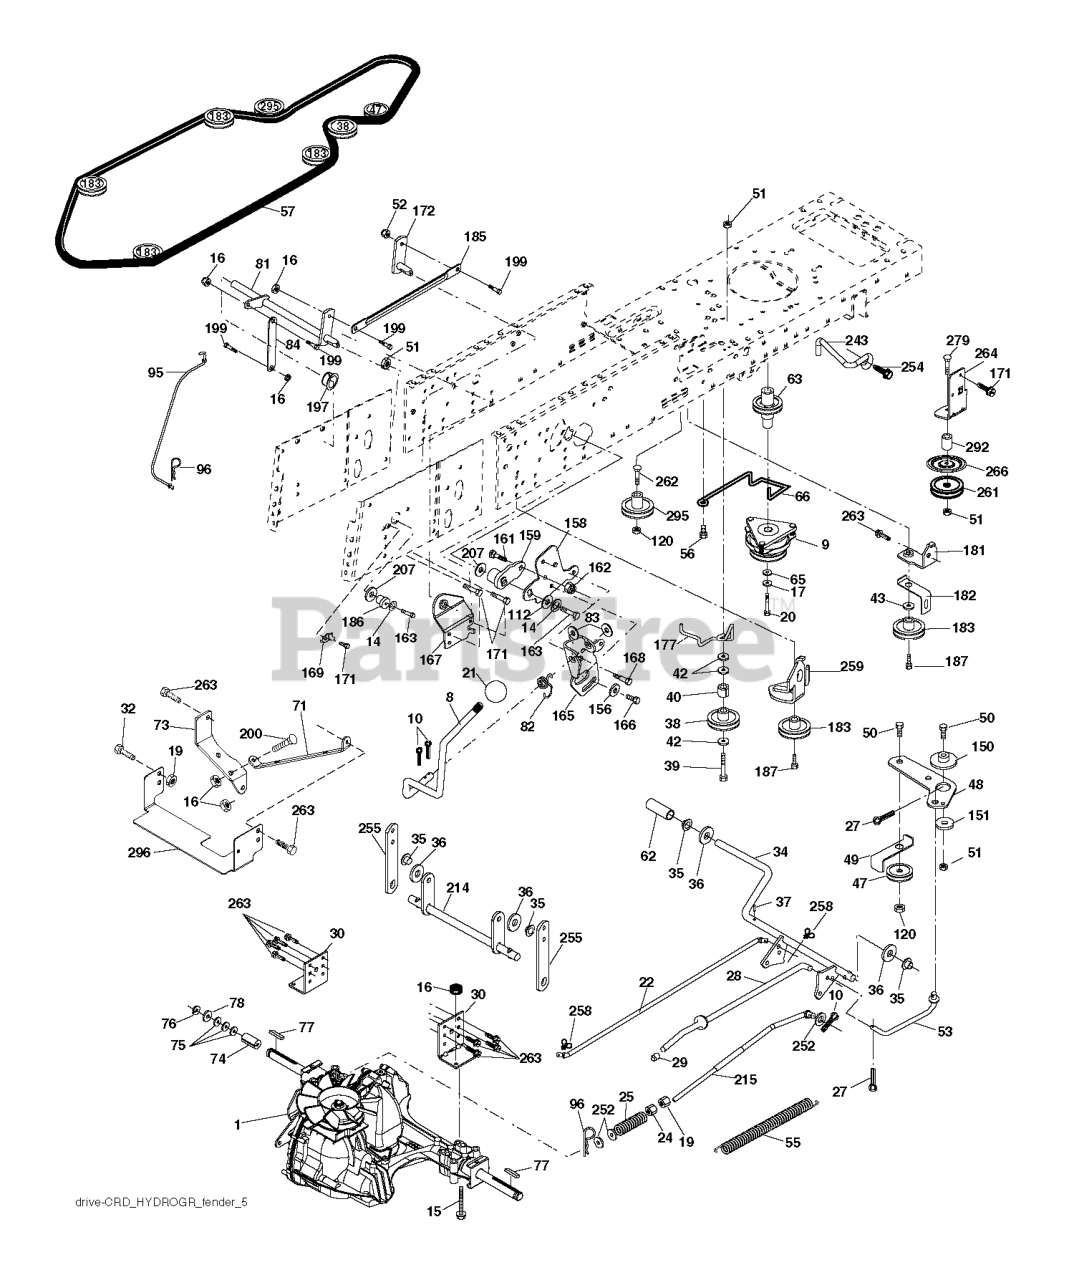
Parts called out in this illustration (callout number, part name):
8	ROD SHIFT FENDER ADJUST LT
9	CLUTCH.ELECTRIC.OGURA.EURO.
10	PIN COTTER
14	LOCKWASHER
15	BOLT HEX 5/16-18 GR 5
16	NUT.71038.31-18.HEX.NYLOCK
19	NUT
20	BOLT HEX 7/16-20X4-1/4"
21	KNOB.DUCKHEAD.1/2
22	ROD
24	NUT
25	SPRING BRAKE ROD
27	COTTER PIN
28	ROD, PARKING BRAKE
29	CAP
30	BRKT, TRNSXLE MNT 20"
32	BOLT D
34	SHAFT, FOOT PEDAL
35	BEARING.NYLON
37	DRIVE PIN
38	PULLEY.FLAT
42	WASHER
47	IDLER PULLEY
48	BELLCRANK, CLUTCH
49	RETAIN BELT
50	BOLT.3/8-16X1.50
52	LOCKNUT
53	LINK.CLUTCH.7.66.2005
55	SPRING, RETURN LT
56	SCREW.3/8-16
57	V-BELT 113"
62	PEDAL COVER T
63	PULLEY.ENGINE.CVX.LT
65	LOCKWASHER
66	KEEPER BELT ENGINE
71	STRAP TORQUE LH HYDRO
73	STRAP TORQUE RH HYDRO
74	SPACER AXLE
77	SQUARE KEY
81	ASM.CROSS.SHAFT.REAR.CRD.0510
82	SHIFT SPRING
83	WASHER
84	LINK.PNT.TRANSAXLE.0510.CRD
95	LINK
96	RETAINER M
120	NUT LOCK FLG 3/8-16 UNC
150	BUSHING.BELLCRANK.GRD.DR
151	WASHER 12/32X2X10GA
156	WASHER.SRRTD.5/16
158	BRACKET
159	RB HUB.SHIFT
161	BOLT
162	NUT.CROWNLOCK.1/4
165	RP BRACKET
166	CAPSCREW.HXHD.FLG.5/16-18X.625
167	BRACKET.SUPT.SHIFT.CRD
168	BOLT.SHOULDER.5/16-18X
169	PLATE.FASTENING.CROSS.SHAFT
172	LINK
181	BRACKET
182	BELT GUIDE
183	PULLEY.V-IDLER.GRND.DR
185	LINK
186	HUB.TAPERED.ROUND.CRD
187	BOLT.5/16-18X1.25
197	NYLINER SNAP 5/8" ID
199	BOLT SHOULDER 5/16-18 UNC
207	WASHER NYL
214	LEVER
215	ROD
243	BRACKET, ANTI-ROTATION
252	WASHER
255	SHAFT
258	CLIP RETAINER
259	BRACKET
261	FLAT IDLER PULLEY
263	SCREW, 3/8-16X3/4
266	PROTECTOR
292	SPACER
295	PULLEY IDLER COMPOSITE
